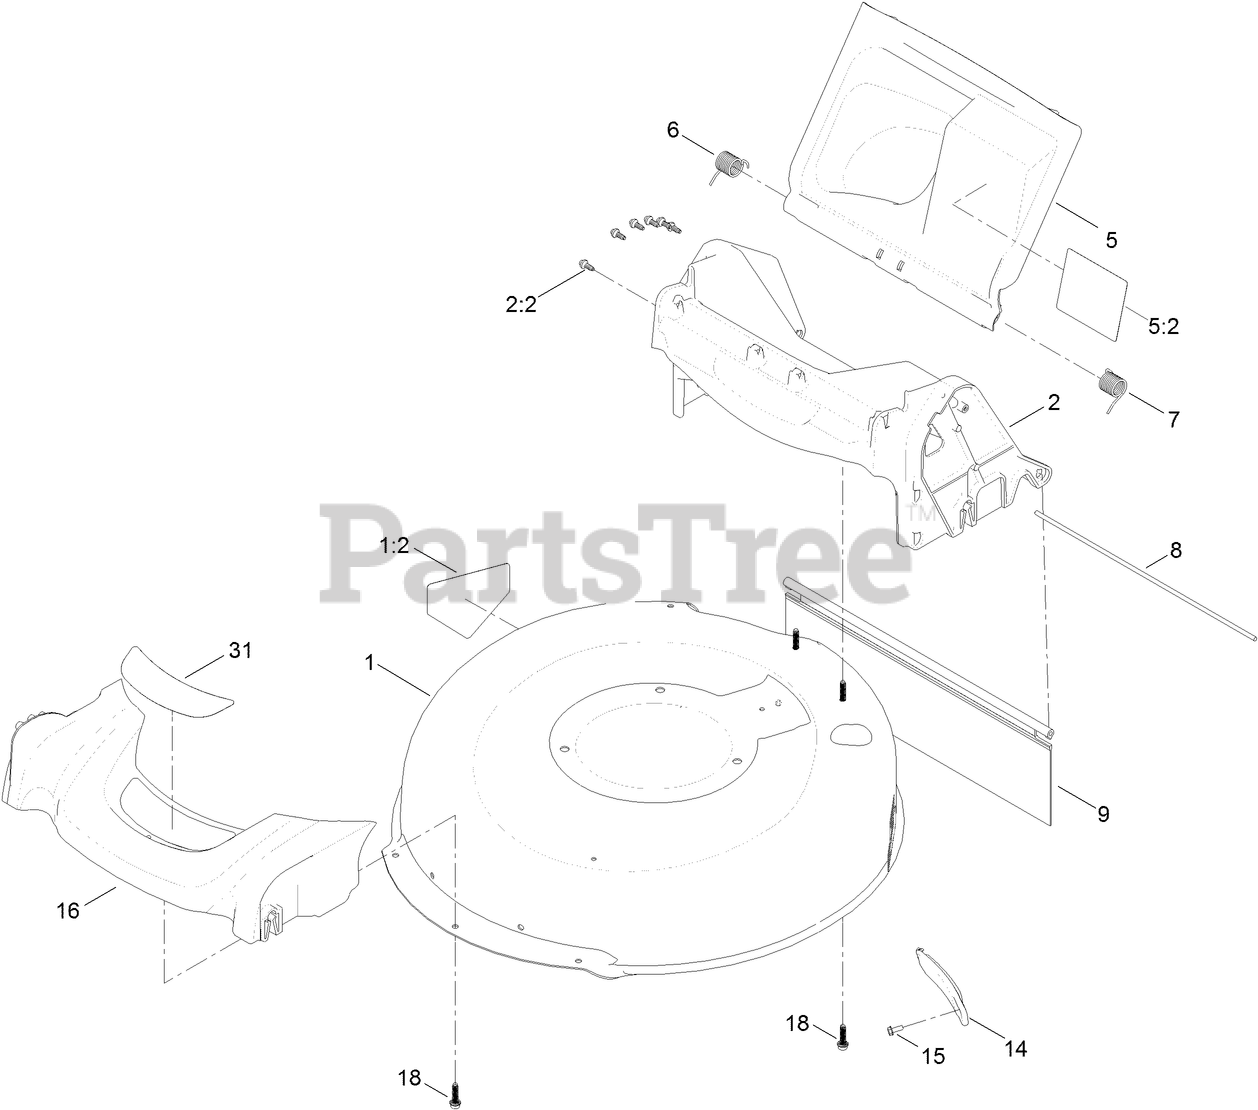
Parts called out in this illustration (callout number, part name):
1:2	DECAL-DANGER
2	CHUTE ASM
5	REAR DEFLECTOR ASM
5:2	DECAL-WARNING
6	SPRING-TORSION
7	SPRING-TORSION
9	SHIELD-TRAILING
14	COVER-BELT
15	SCREW-TAPTITE
18	SCREW-FLANGE, PLASTIC
31	DECAL-DECK
